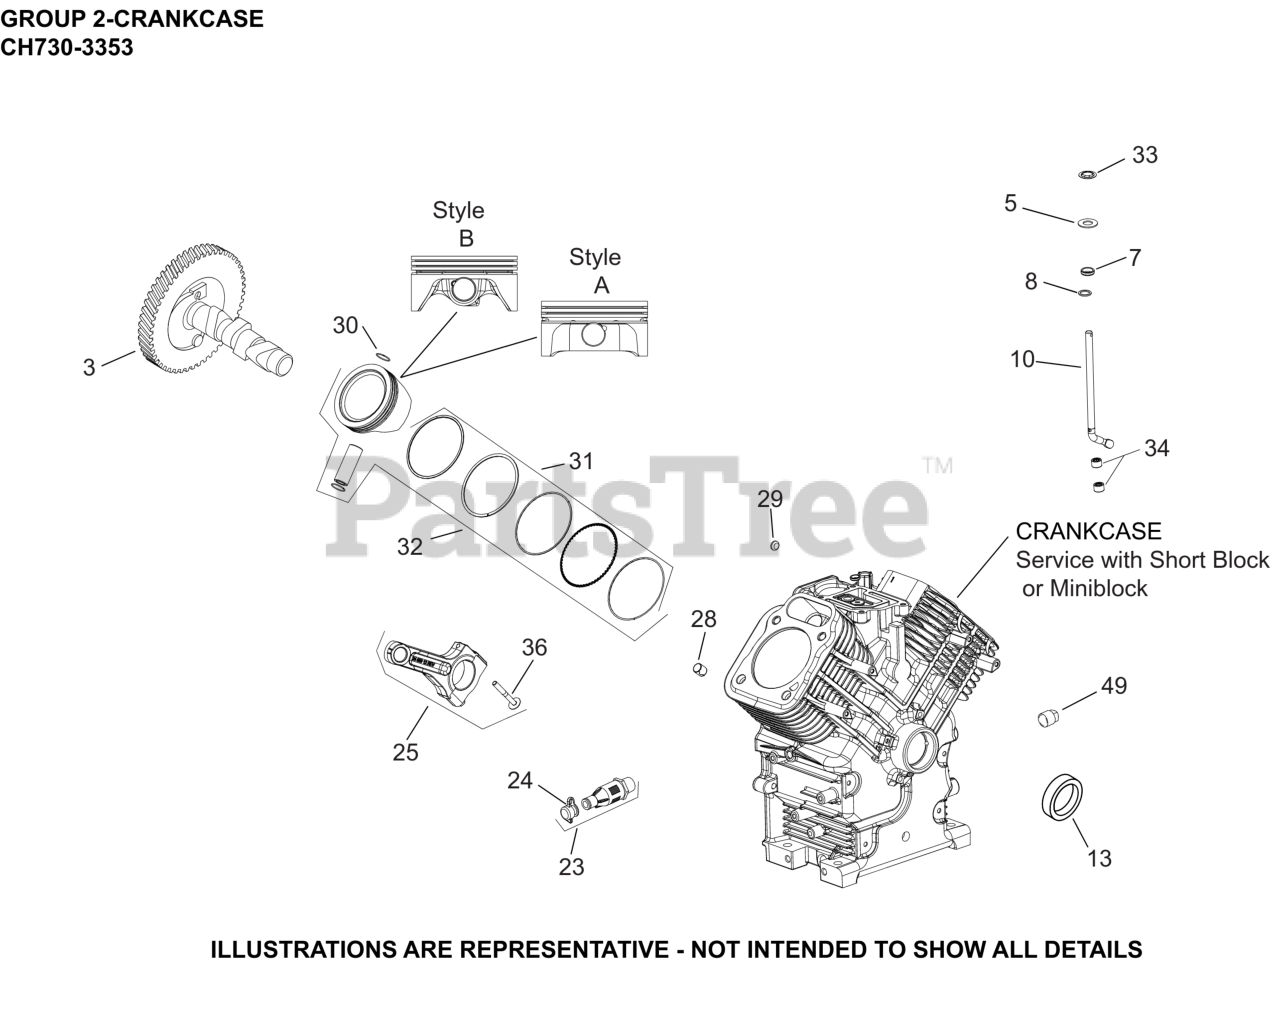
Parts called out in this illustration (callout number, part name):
3	KIT, CAMSHAFT-(#2401225S)
5	WASHER, FLAT 9 MM
7	SEAL, GOVERNOR CROSS SHAFT
8	WASHER, FLAT 11/32"
10	SHAFT, GOVERNOR CROSS
13	SEAL, OIL (HELIX LIP)
23	KIT, OIL DRAIN VALVE
24	CAP, OIL DRAIN VALVE
25	ROD, ASSEMBLY CONNECTING
28	PIN, LOCATING
29	PLUG, CUP
30	RETAINER, PISTON PIN
31	RING SET(STD)STYLE B-1.2mm Tp RING THICK
31	RING SET(.08)STYLE B-1.2mm RING THICK
31	RING SET(.25)STYLE B-1.2mm Tp RING THICK
31	RING SET(.50)STYLE B-1.2mm Tp RING THICK
32	KIT, PISTON 725CC (STD) STYLE B
32	KIT, PISTON 725CC (.08) STYLE B
32	KIT, PISTON 725CC (.25) STYLE B
32	KIT, PISTON 725CC (.50) STYLE B
33	RETAINER, RING
34	BEARING, NEEDLE
36	KIT, ROD BOLTS-(#25086677S)
49	PLUG, SQ HD PIPE 3/8"
